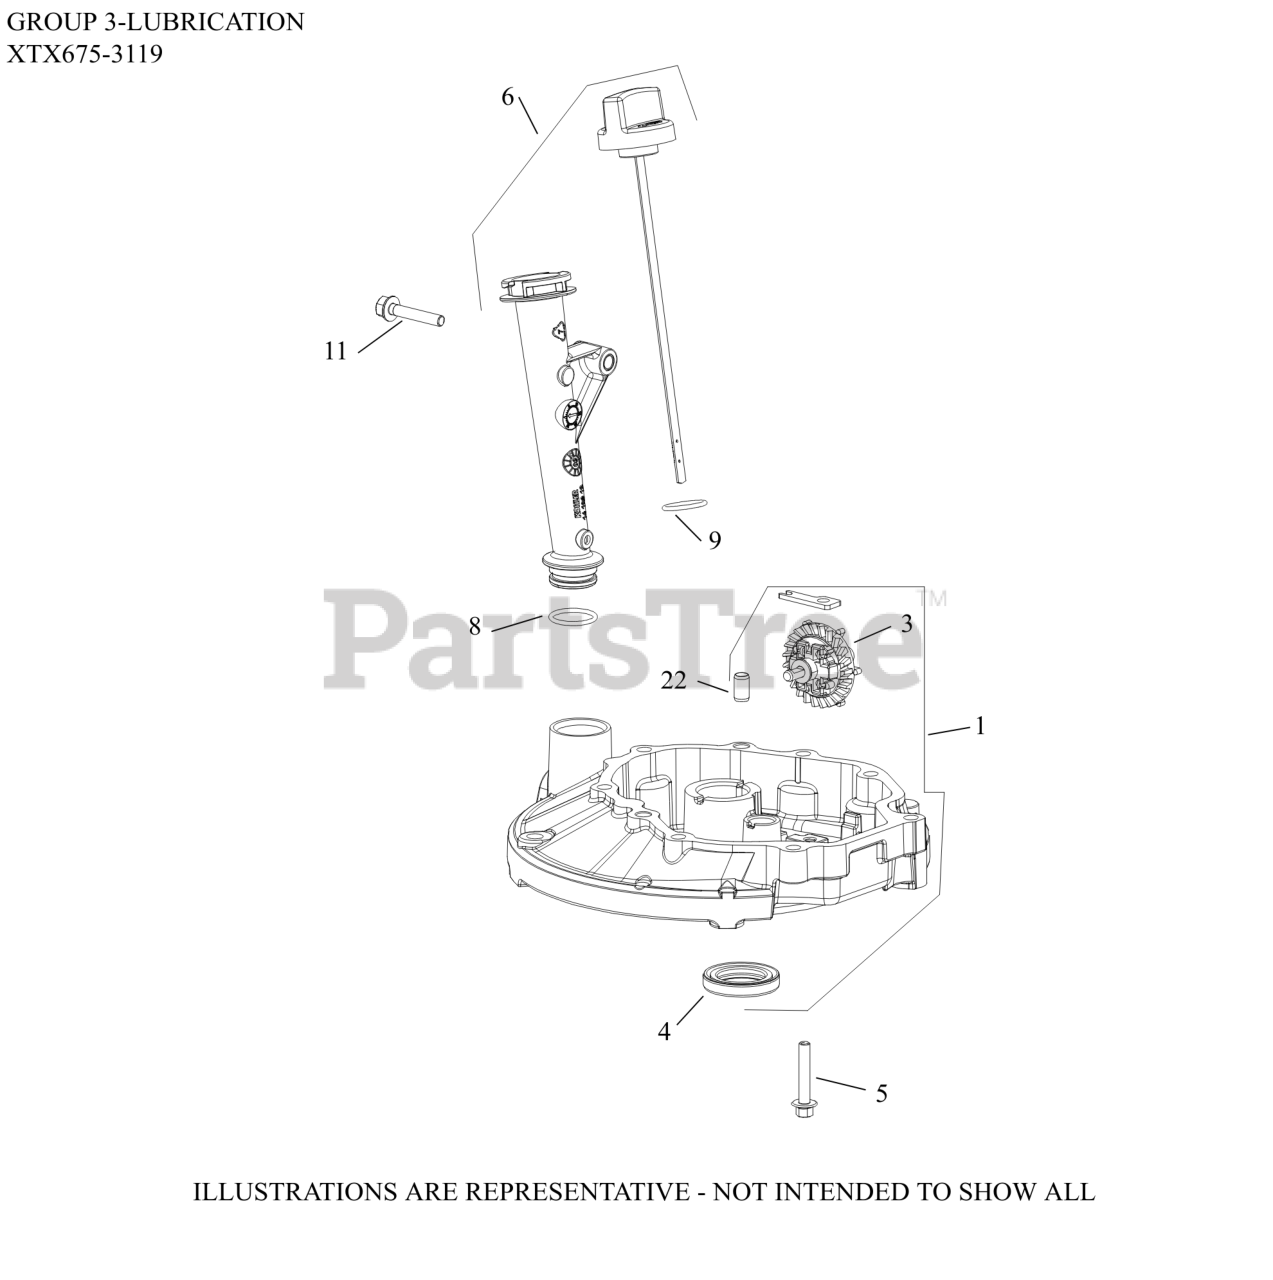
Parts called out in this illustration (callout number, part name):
1	KIT, OIL PAN
3	GEAR ASSEMBLY, GOVERNOR
5	SCREW, HEX FLANGE (M6)-(#25086434S)
6	TUBE ASSEMBLY OIL FILL
8	O-RING, OIL FILL TUBE
9	O-RING (CAP)
11	SCREW, HEX FLANGE (M6)-(#25086435S)
22	PIN, DOWEL (8mm)
